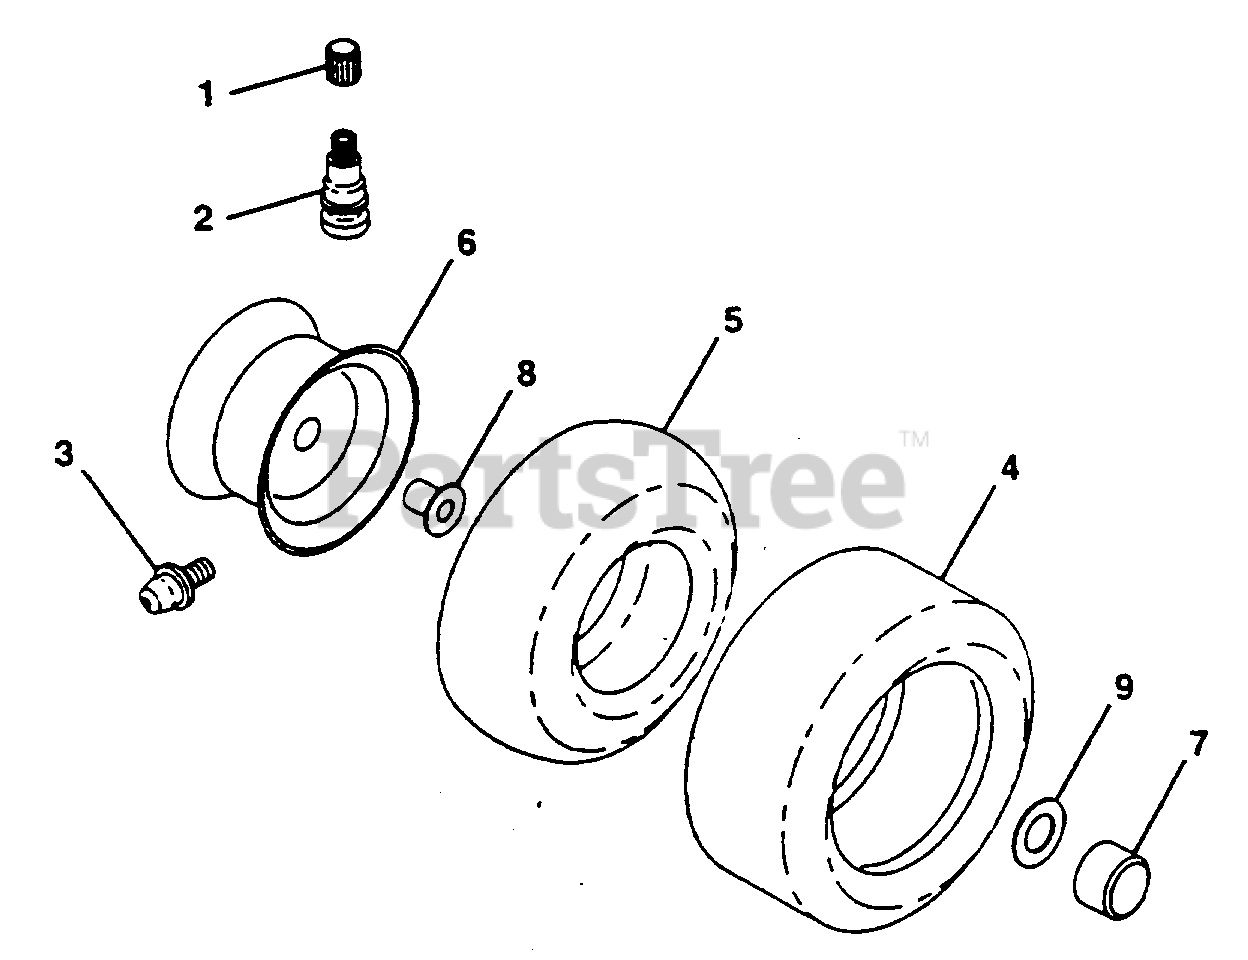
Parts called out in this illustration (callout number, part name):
1	Cap, Valve (AYP part number)
2	Stem, Valve (AYP part number)
3	Fitting, Grease (Front Wheels Only) (AYP part number)
4	Tire, Front (AYP part number)
4	Tire, Rear (AYP part number)
5	Tube, Front (Optional Service Items Only)
5	Tube, Rear (Optional Service Items Only) (AYP part number)
6	Rim, Front (AYP part number)
6	Rim, Rear
7	Cap, Axle (AYP part number)
8	Bearing, Flange (AYP part number)
9	Washer 25/32 x 1-5/8 x 16 Ga. (AYP part number)
